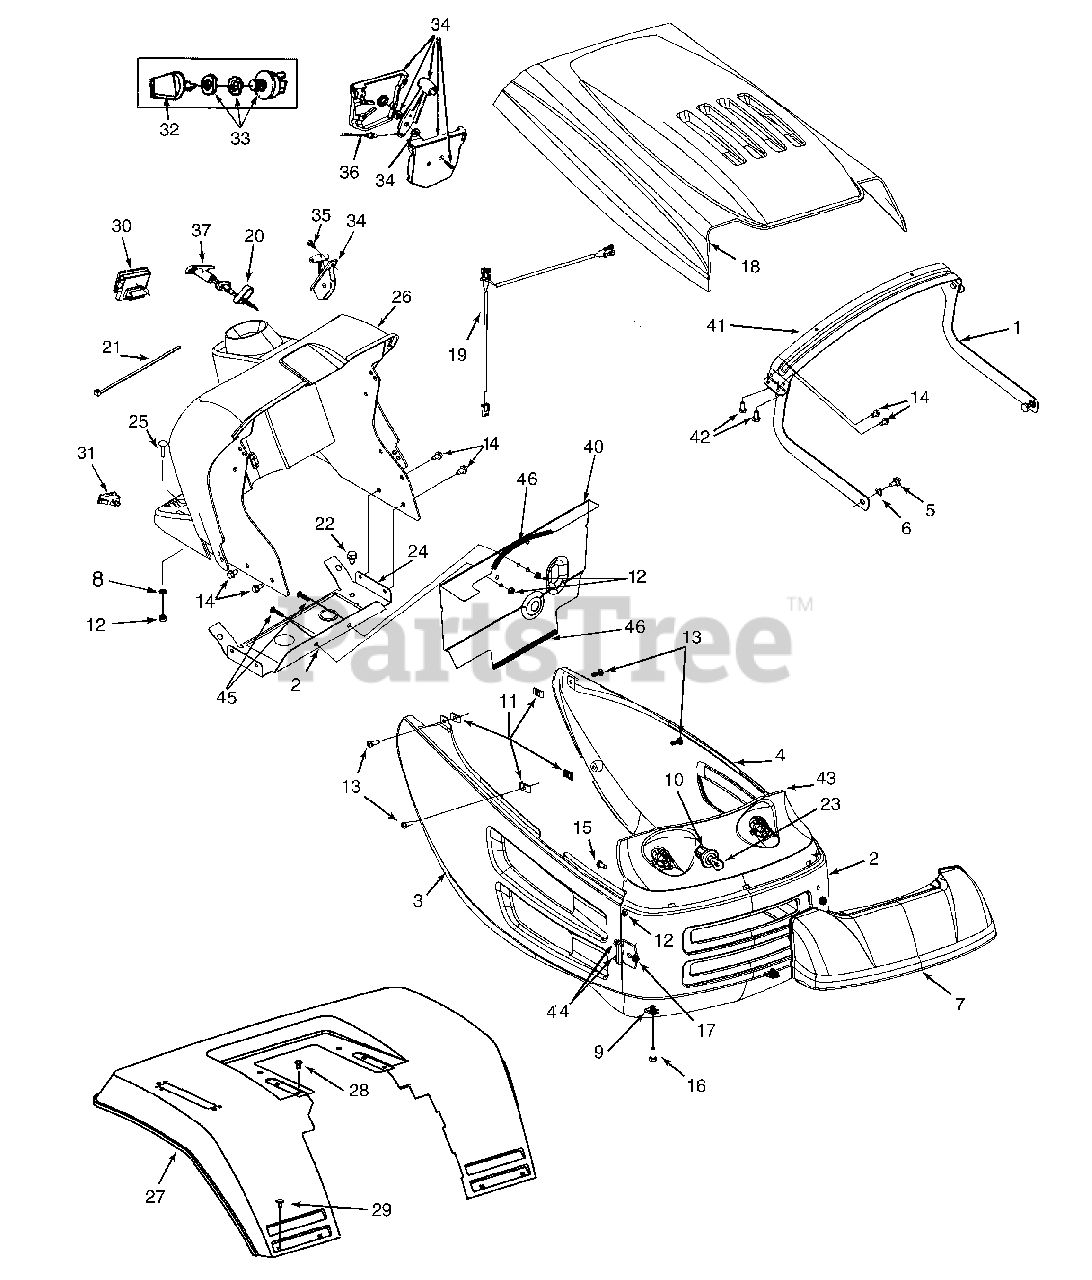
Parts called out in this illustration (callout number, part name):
6	Spr. Wash. .39" I.D. x .62" O.D.
7	Lens
8	Retainer Nut
9	U - Nut 5/16-18 Thd
10	Socket
11	Tinn. Nut 1/4-20 Thd.
12	Hex Sems Nut 1/4-20 Thd.
13	Pan Hd. Mach. Scr. 1/4-20 x .75" Lg.
14	Hex Wash. Hd. TT-Tap Scr. 1/4-20 x .5" Lg.
15	Hex Bolt 1/4-20 x .625" Lg.
16	Hex Bolt 5/16-18 x .1" Lg. (Gr.5)
19	Headlight Harness
20	Choke Retainer
21	Cable Tie
22	Hex Wash. Hd. Tap Scr. 5/16-18 x .5"
23	Lamp
26	Dash Panel
29	Truss Mach. Scr. 1/4-20 x .5" Lg.
30	Ammeter
31	Light Switch
32	Ignition Key
33	Ignition Switch
34	Throttle Box Ass'y.
35	Truss Mach. AB-Tap Scr. #10 x .5"
36	Throttle Control Wire 18.5 Lg.
37	Choke Control 20" Lg.
43	Retainer Nut
44	Hex Wash. Hd. AB-Tap Scr. 1/4-14 x .625" Lg.
45	Pan Hd. Scr. 1/4-20 x 1" Lg.
46	Trim Strip
